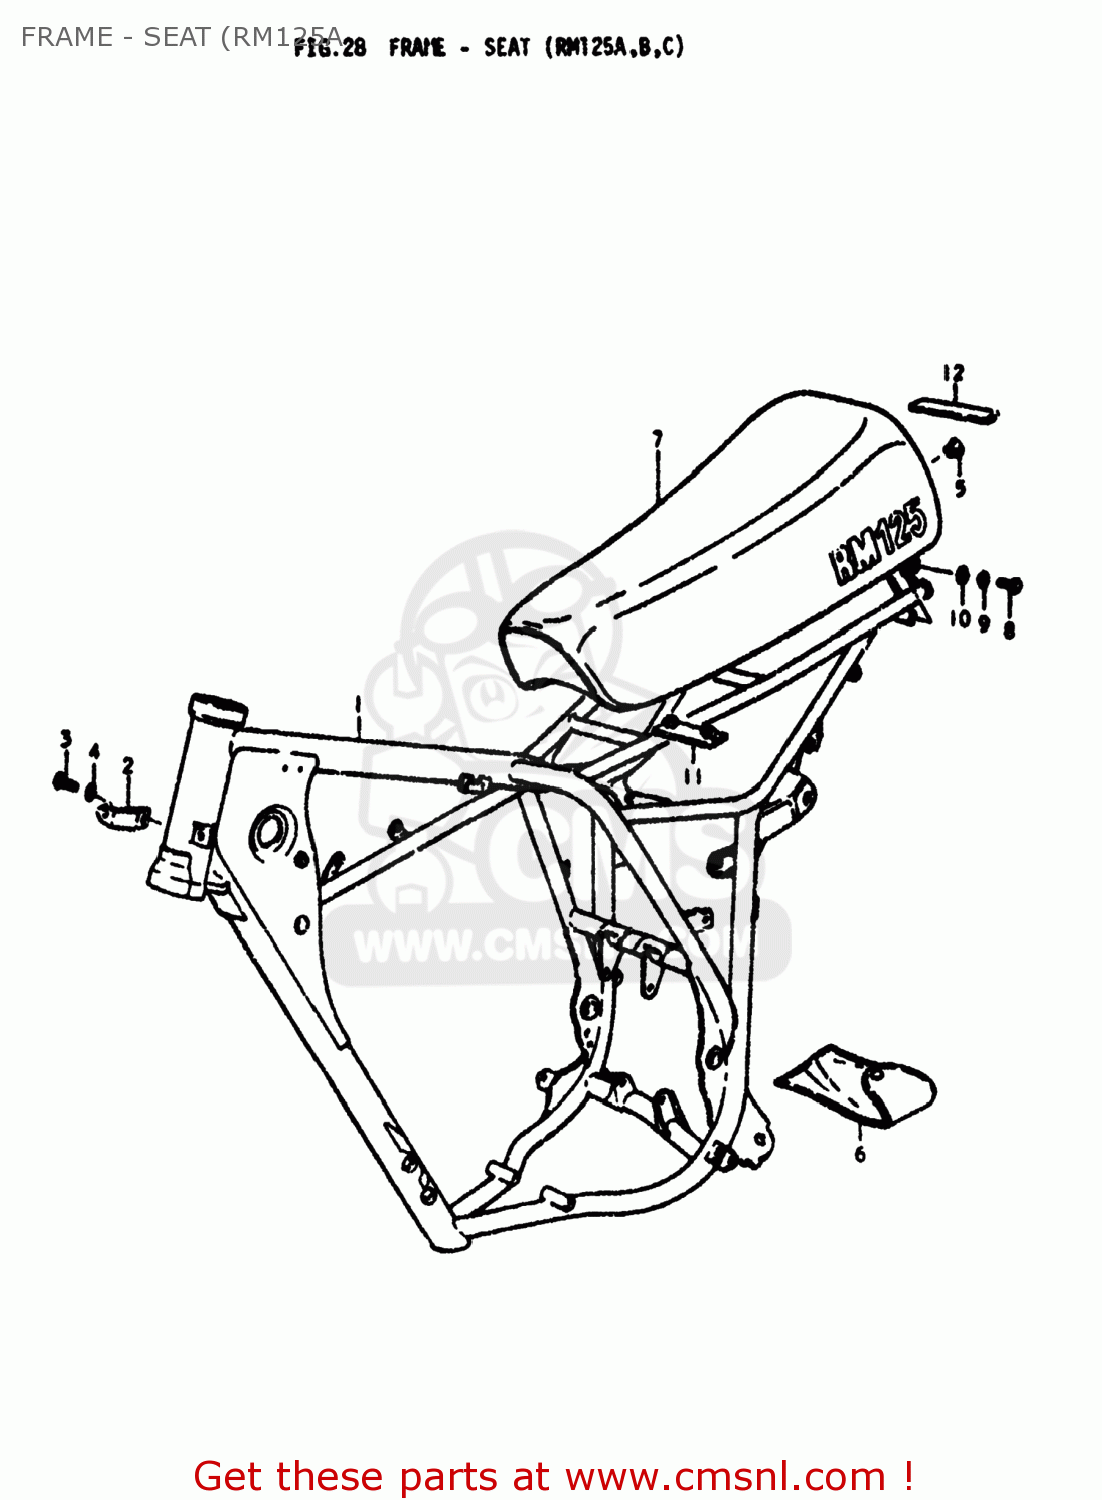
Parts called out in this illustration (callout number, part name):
1	FRAME
2	PLATE,ENGINE MOUNTING
3	BOLT
4	LOCK WASHER
5	CAP(OD:17)
7	SEAT ASSEMBLY
8	BOLT
9	LOCK WASHER
10	WASHER
11	CUSHION
12	CUSHION,FRAME
